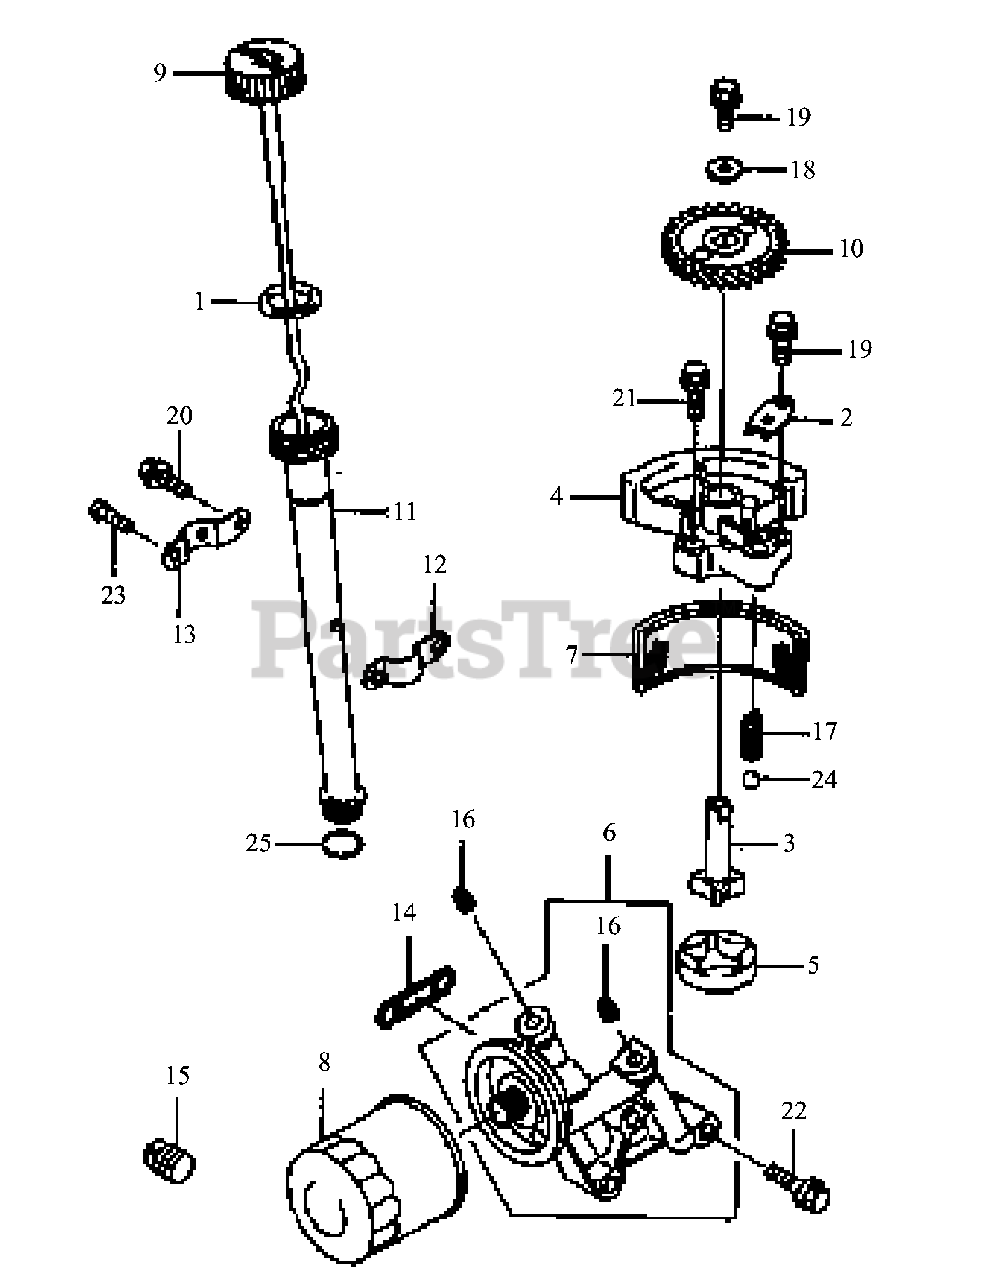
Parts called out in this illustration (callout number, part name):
1	Gasket, Oil Guage
3	Pump, Assembly Oil
8	Filter, Oil
10	Gear, Helical
19	Bolt, Flange
20	Bolt, Flange
21	Bolt, Flange
22	Bolt, Flange
24	Ball, Steel
